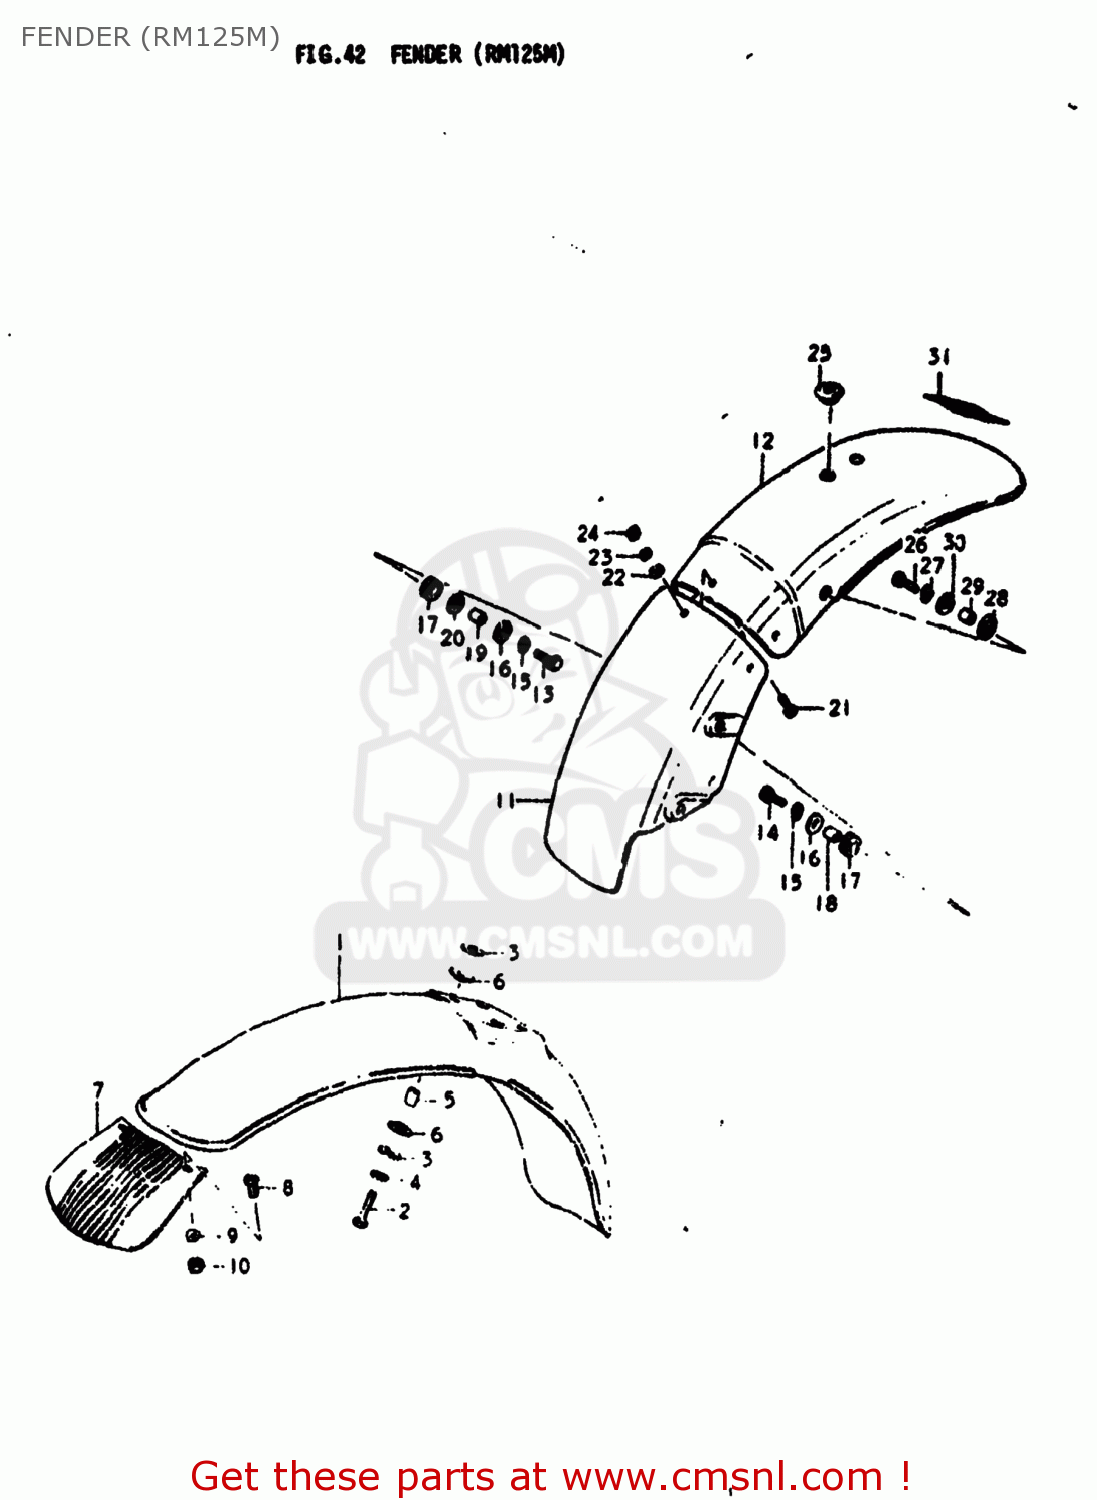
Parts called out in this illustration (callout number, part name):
1	FENDER,FRONT
2	BOLT
3	WASHER (6.5X24X1.2)
4	LOCK WASHER
5	SPACER (6.5X10.5X13.5)
6	CUSHION
7	MUD FLAP,FRONT FENDER
8	SCREW
9	WASHER (5.5X18X1)
10	NUT
11	FENDER,REAR
12	FENDER,REAR
13	BOLT
14	BOLT
15	LOCK WASHER
16	WASHER (6.5X20X1.2)
17	CUSHION
18	SPACER(6.1X9X7.5)
19	SPACER (6.1X8X12)
20	CUSHION
21	SCREW
22	WASHER 5MM
23	LOCK WASHER
24	NUT
25	CAP
26	BOLT(6X18)
27	LOCK WASHER
28	CUSHION
29	SPACER(6.1X9X7.5)
30	WASHER (6.5X20X1.2)
